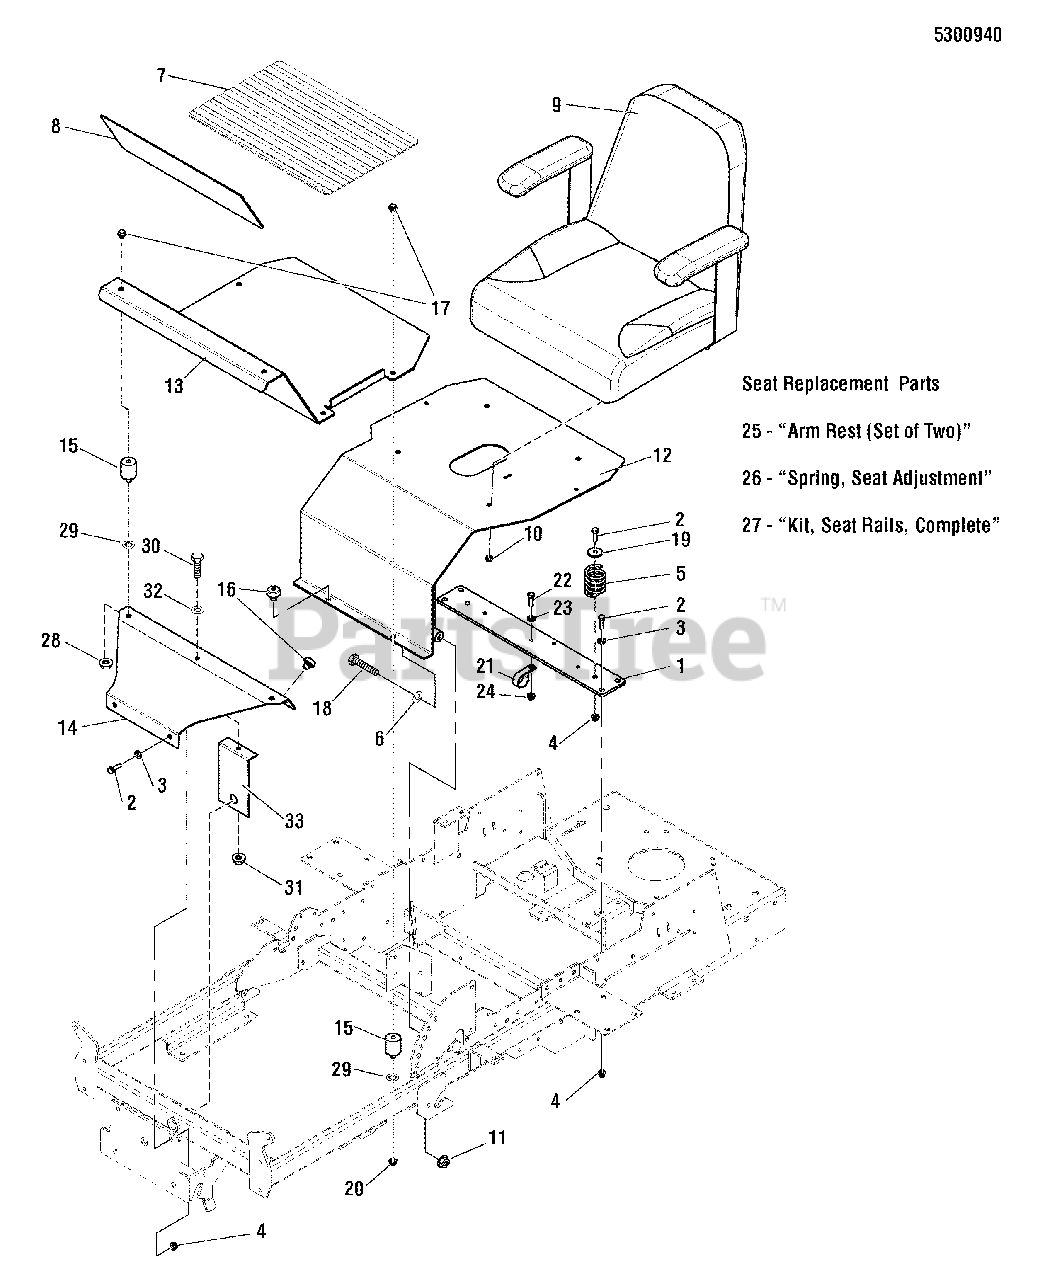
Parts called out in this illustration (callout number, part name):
1	PLATE, SEAT SUPPORT, CONS Z - ORG
2	BOLT, 5/16-18 X 1 GD5 YZ
3	WASHER, 5/16 GD.9 FLAT
4	NUT, 5/16-18 HEX NYLOCK FLANGE
5	SPRING, SEAT SUPPORT
6	WASHER, 3/8 SAE
7	SAFETY WALK, FLOOR PLATE, 17.38 X 11.50
8	SAFETY WALK, FLOOR REST, 17.38 X 6.00
9	SEAT, XB-180, NO LOGO, BLACK
10	NUT, 5/16-18 HEX NYLON LOCK
11	NUT, 3/8-16 HEX NYLOCK FLANGE
12	WELD, SEAT PLATE - ORG
13	PLATE, FLOOR, CONSUMER Z - ORG
14	PLATE, FLOOR, FRONT, CONS Z - ORG
15	MOUNT, VIBRATION, 30 DURO
16	MOUNT, VIBRATION, RUBBER
17	BOLT, 3/8-16 X 5/8, SERRATED UNDER HEAD
18	BOLT, 3/8-16 X 3-1/2 GD5 YZ
19	WASHER, .34 X 1.25 X 10 GA
20	NUT, 3/8-16 HEX SERRATED FLANGE
21	CLAMP, VINYL INSULATED
22	BOLT, 1/4-20 X 3/4 GD5 YZ
23	WASHER, 1/4 SAE (5025154)
24	NUT, 1/4-20 HEX NYLOCK FLANGE (5025391)
25	ARM REST, SET OF TWO (SV)
26	SPRING, EXTENSION, SEAT ADJUSTMENT (BLK OR SLVR)
27	KIT, SEAT RAILS. COMPLETE (SV)
28	NUT, 3/8-16 HEX NYLOCK FLANGE
29	WASHER, 3/8" ID, INTERNAL TOOTH
30	BOLT, 5/16-18 X 3/4 GD5
31	NUT, 5/16-18 HEX NYLOCK FLANGE
32	WASHER, 5/16 SAE
33	PLATE, SUPPORT, FRONT FLOOR - ORG
